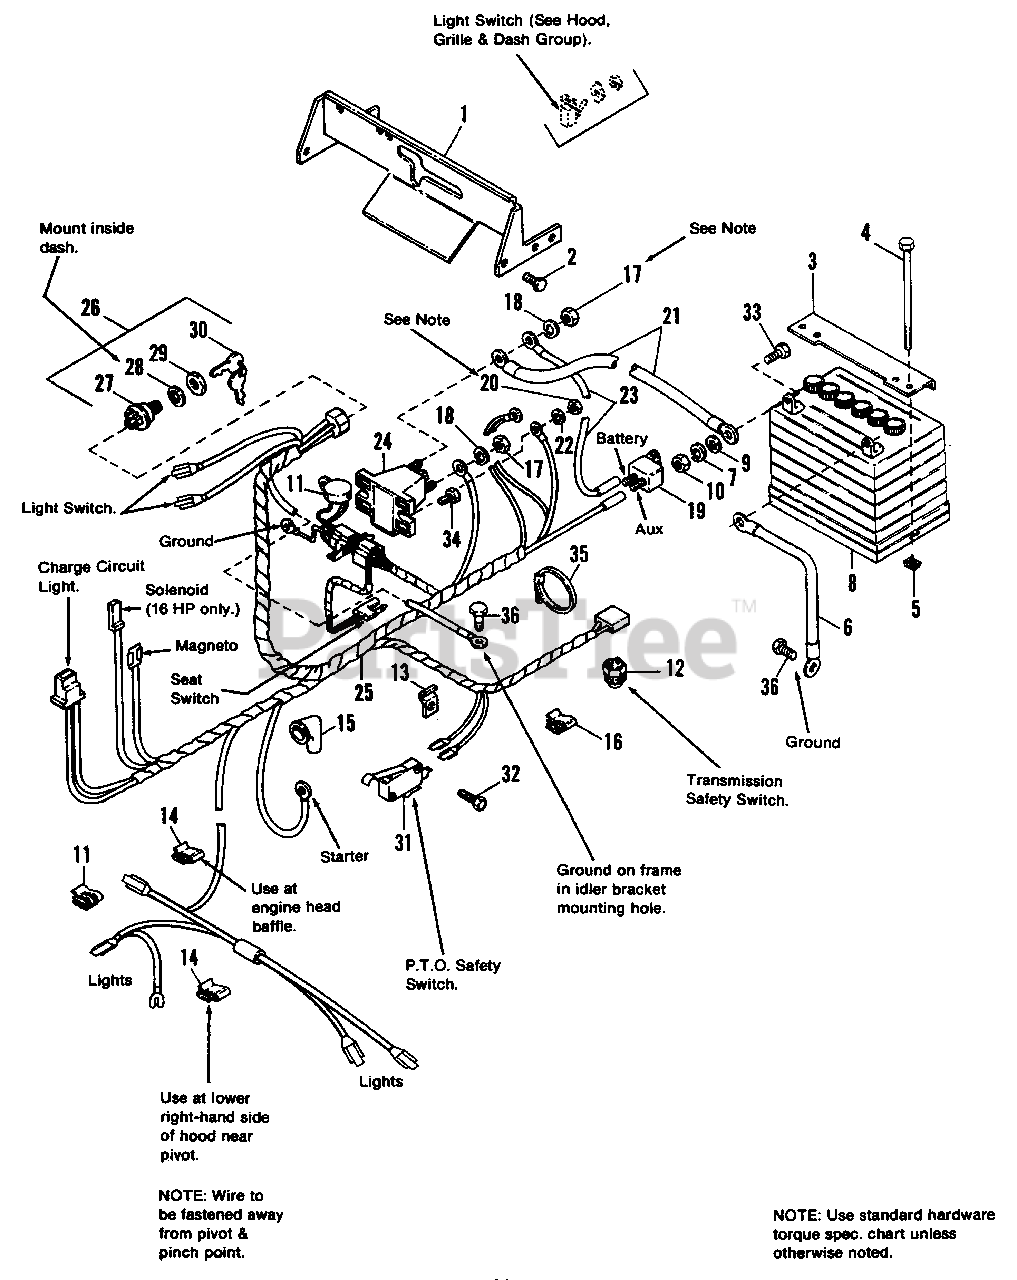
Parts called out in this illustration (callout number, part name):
1	QUADRANT, Shift
2	SCREW, Hex, Taptite, 1/4-20 x 3/8
3	HOLD DOWN, Battery
4	CAPSCREW, Hex Hd., 1/4-20 x 7
5	NUT, Retainer, 1/4-20
7	LOCKWASHER, 1/4
8	BATTERY SERVICE KIT, 39 Amp (includes decal)
9	WASHER, Plain, 1/4
10	NUT, Hex, Full, 1/4-20
11	MODULE, DSI INTERLOCK
12	SWITCH, Interlock
14	CLIP, Wire
15	COVER, Terminal
16	CLIP, Speed
17	NUT, Hex, Full, 5/16-24
18	LOCKWASHER, 5/16
19	BREAKER, Circuit
20	NUT, Hex, Full #10-32
22	LOCKWASHER, External, #10
24	SOLENOID
25	HARNESS, Wiring (1691095 & 1691272 only)
25	HARNESS, WIRING (All Models except 1691095 & 1691272)
26	SWITCH, Ignition (Incl. Ref. Nos. 29 & 30)
28	LOCKWASHER, Internal, 5/8
29	NUT, Hex, 5/8-32
31	SWITCH, P.T.O., Interlock
32	SCREW, Taptite, #5-40 x 3/4
33	CAPSCREW, 1/4-20 x 3/4
34	SCREW, Taptite, 1/4-20 x 5/8, Zinc Plt.
36	SCREW, Hex, Taptite, 1/4-20 x 3/8 Zinc Pltd.
